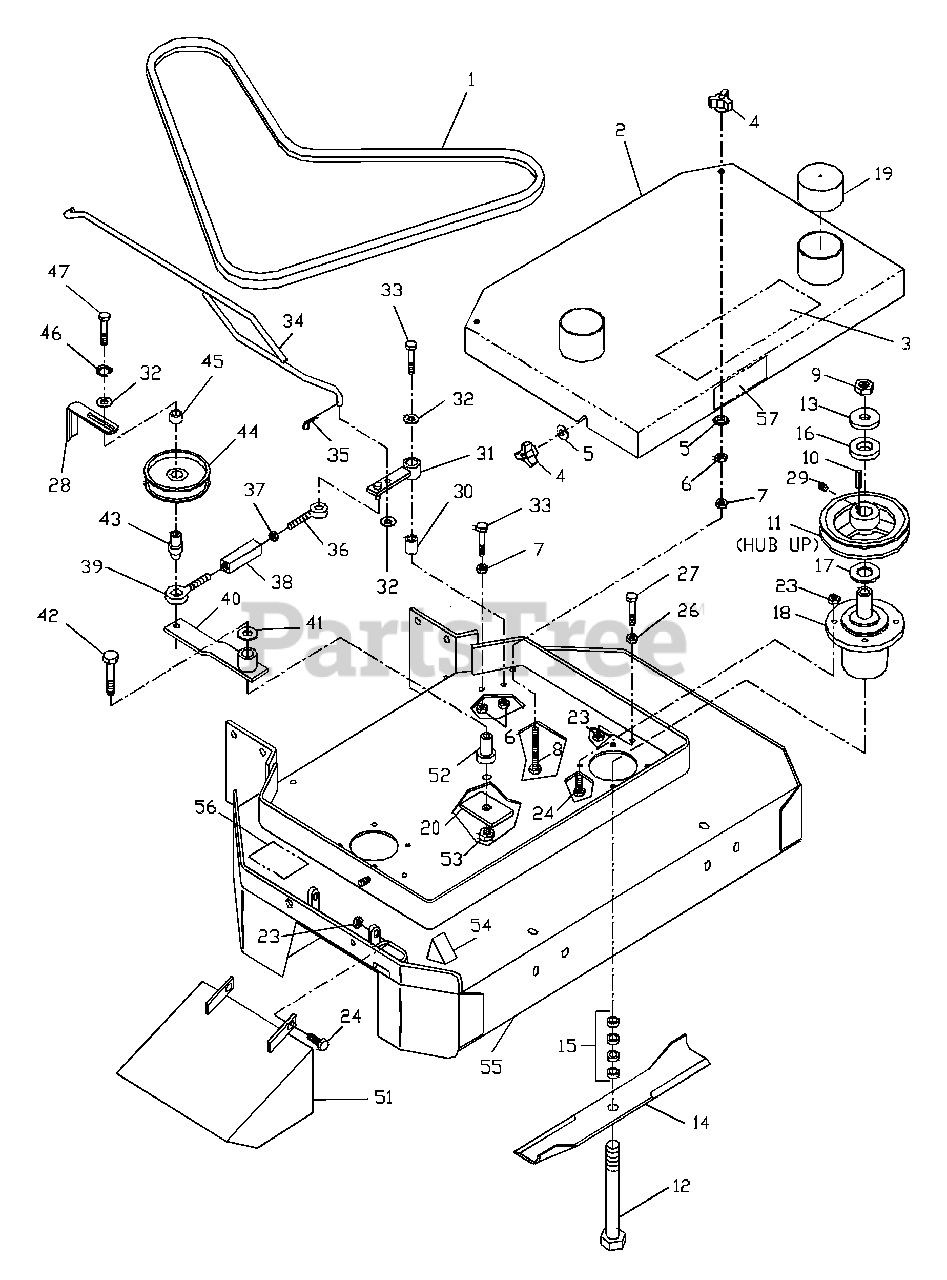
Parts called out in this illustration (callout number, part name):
1	36" DECK BELT
2	36" BELT SHIELD
3	DECAL, HUSQVARNA
4	THREE PRONG KNOB
5	3/8 SEALING WASHER
7	3/8C WHIZ NUT
8	TAPBOLT 3/8C X 4 1/2
10	KEY 1/4SQ. X 1 1/8
11	PULLEY W/SETSCREWS
12	HCS 5/8F X 8 1/2
13	SUPPORT WASHER
14	BLADE 18"(36)
15	BLADE SPACERS
17	MACH. BUSHING 10GA.
18	HOUSING ASM.
24	HCS 5/16C X 1
26	HFLN 5/16C
27	HCS 5/16C X 3
29	5/16 NYLOC SETSCREW
30	SLEEVE BUSHING
31	ENGAGEMENT ARM
32	FW 3/8 STD
33	HCS 3/8C X 2 1/4
35	#2 HAIRPIN
36	RT. HAND EYEBOLT
37	5/16C HEX NUT
38	TURNBUCKLE
39	LT. HAND EYEBOLT
41	FW 1/2 STD
42	HCS 1/2C X 2 3/4
43	EYEBOLT PIVOT
44	IDLER PULLEY
46	3/8 LOCK WASHER
47	HCS 3/8C X 2 1/2
51	DEFLECTOR CHUTE
52	IDLER SPINDLE
53	HLN 1/2C NYLOC
54	DECAL, CPSC
55	36" DECK W/DECALS
56	DECAL, DANGER
57	DECAL, NASCAR
